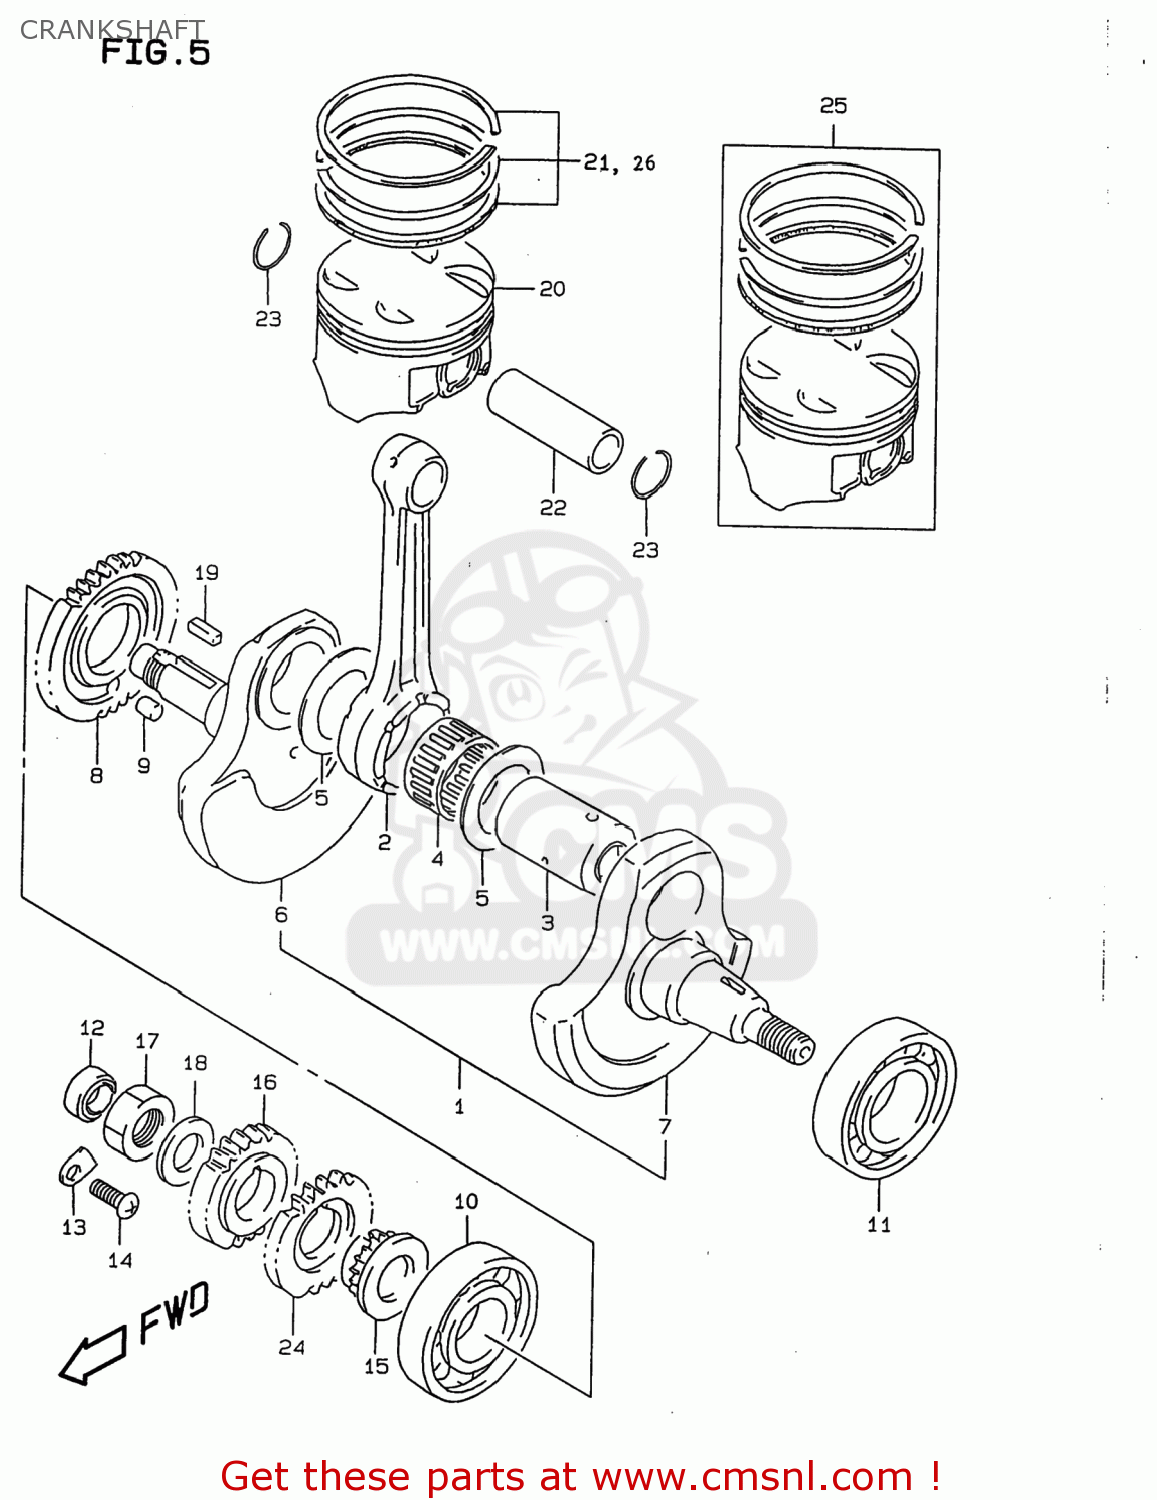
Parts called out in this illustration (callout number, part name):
1	CRANKSHAFT ASSY
2	ROD,CONNECTING
3	PIN COMP,CRANK
4	BEARING(34X43X22)
5	WASHER(34X52X1)
6	CRANKSHAFT,R
7	CRANKSHAFT,L
8	GEAR,CRANK BAL DRIVE(NT:37)
9	PIN
10	BEARING(30X72X19)
11	BEARING 35X72X17
12	SEAL,OIL(14X24X6)
13	RETAINER,BEARING
14	SCREW
15	SPROCKET,CAM CHAIN DRIVE
16	GEAR,PRIMARY DRIVE
17	NUT
18	WASHER
19	KEY
20	PISTON
21	RING SET,PISTON
22	PIN,PISTON
23	CIRCLIP,PISTON PIN
24	GEAR,OIL PUMP DRIVE (NT
25	PISTON SET(OS:0.5)
